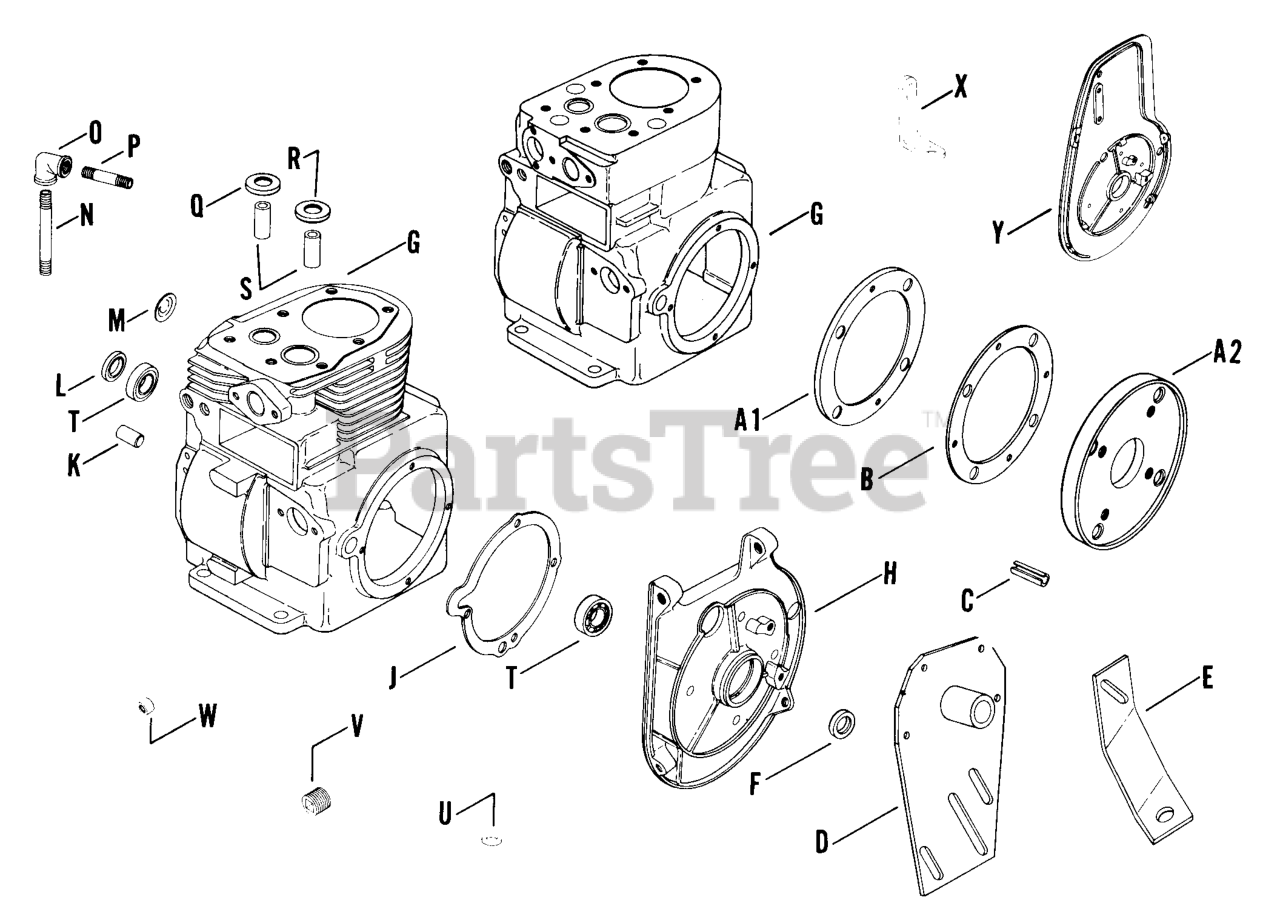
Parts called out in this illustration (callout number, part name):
H	PLATE - (#DSC)
M	PLUG, WELCH EXPANSION
Q	INSERT - DISCONTINUED
T	BEARING - DISCONTINUED
U	WASHER - USE 41 468 01
W	BEARING - USE 234866
